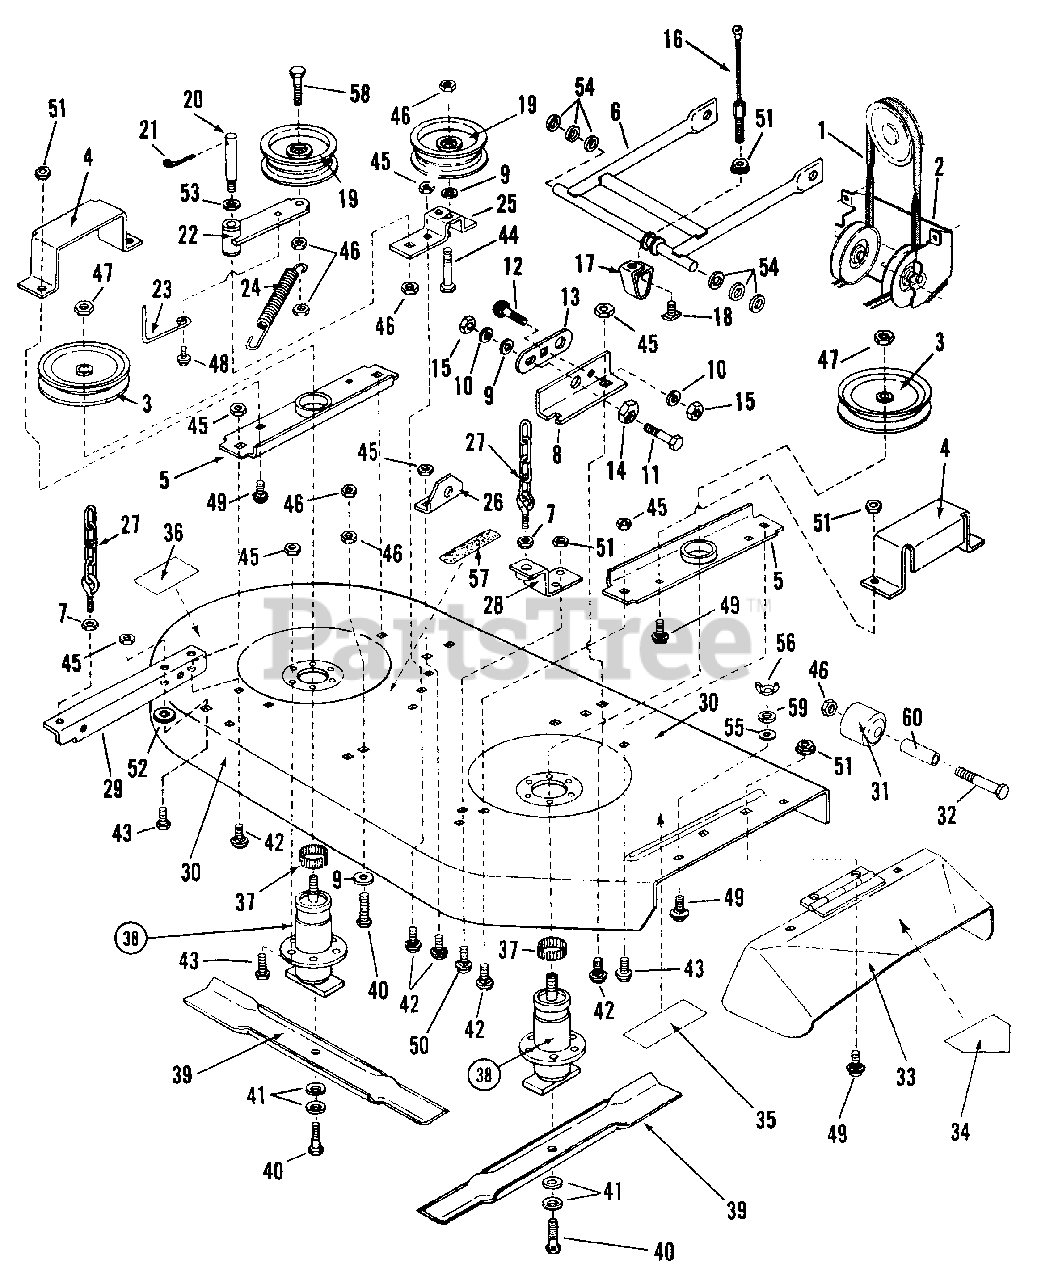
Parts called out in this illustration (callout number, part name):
1	BELT, 41" Mower (A137)
2	ASSEMBLY, Mule Drive
3	PULLEY, 5-3/4" O.D.
4	GUARD, Pulley
5	BRACE, Spindle
6	WELDMENT, Front Lift Arm
7	JAM-NUT, 3/8-16 Hex
8	BRACKET, Right Front
9	WASHER, 3/8" Flat
10	WASHER, 3/8 Split Lock
11	SCREW, 3/8-16 x 1" Hex Head
12	BOLT, 3/8-16 x 3/4" Square Neck Carriage, Grade 5
13	LINK, Adjustment
14	RING, Adjustment
15	NUT, 3/8-16 Hex
16	CABLE, Front Lift
17	BRACKET, Fr. Lift Arm Hanger
18	T-NUT, 5/16-18
19	PULLEY, 4.1 O.D.
20	STUD, Idler (3/8-24)
21	COTTER-PIN, 1/8 x 1"
22	ASY, Idler Arm
23	GUIDE, Belt
24	SPRING, Idler Arm
25	BRACKET, Idler
26	BRACKET, Front Left Hanger
27	ASY, 3/8 Bolt/Chain
28	BRKT, Rear Rt. Supp. (1985)
29	BRKT, Rear Left Supp.(1985)
30	MOWER DECK, 41"
31	WHEEL, Gage
32	SCREW, 3/8-24 x 3-3/4" Hex Head Cap, Grade 5
33	DEFLECTOR, (Side Chute)
34	DECAL, Danger
35	DECAL, Caution (Deflector)
36	DECAL, Caution (Rot. Blades)
37	RING, Tolerance, 3/4"
38	ASY, Spindle
39	BLADE, 21" Cutter
40	SCREW, 3/8-24 x 1-1/4" Hex Head Cap, Grade 5
41	CONE-WASHER
42	Carriage Bolt, 3/8"-16x3/4"
43	BOLT, 3/8-16 x 3/4" HFL
44	SCREW, 3/8-24 x 1-3/4" Hex Head cap, Grade 5
45	NUT, 3/8-16 Hex Fl. Lock
46	NUT, 3/8-24 Hex Ctr. Lk.
47	NUT, 3/4-16 Jam Lock
48	SCREW, 1/4-20 x 5/8" HWST
49	BOLT, 5/16-18 x 5/8" Square Neck Carriage, Grade 5
50	BOLT, 5/16-18 x 1/2" Hex Flange Lock, Grade 5
51	NUT, 5/16-18 Hex Flange Lock, Grade 5
52	WASHER, 3/8" Flat
53	WASHER, 5/8 Flat
54	WASHER, Spacer
55	RETAINER, 5/16 Bolt
56	WING-NUT, 5/16-18
58	SCREW, 3/8-24 x 2" Hex Head Cap, Grade 5
59	WASHER, 5/16 Split Lock
60	SPACER
